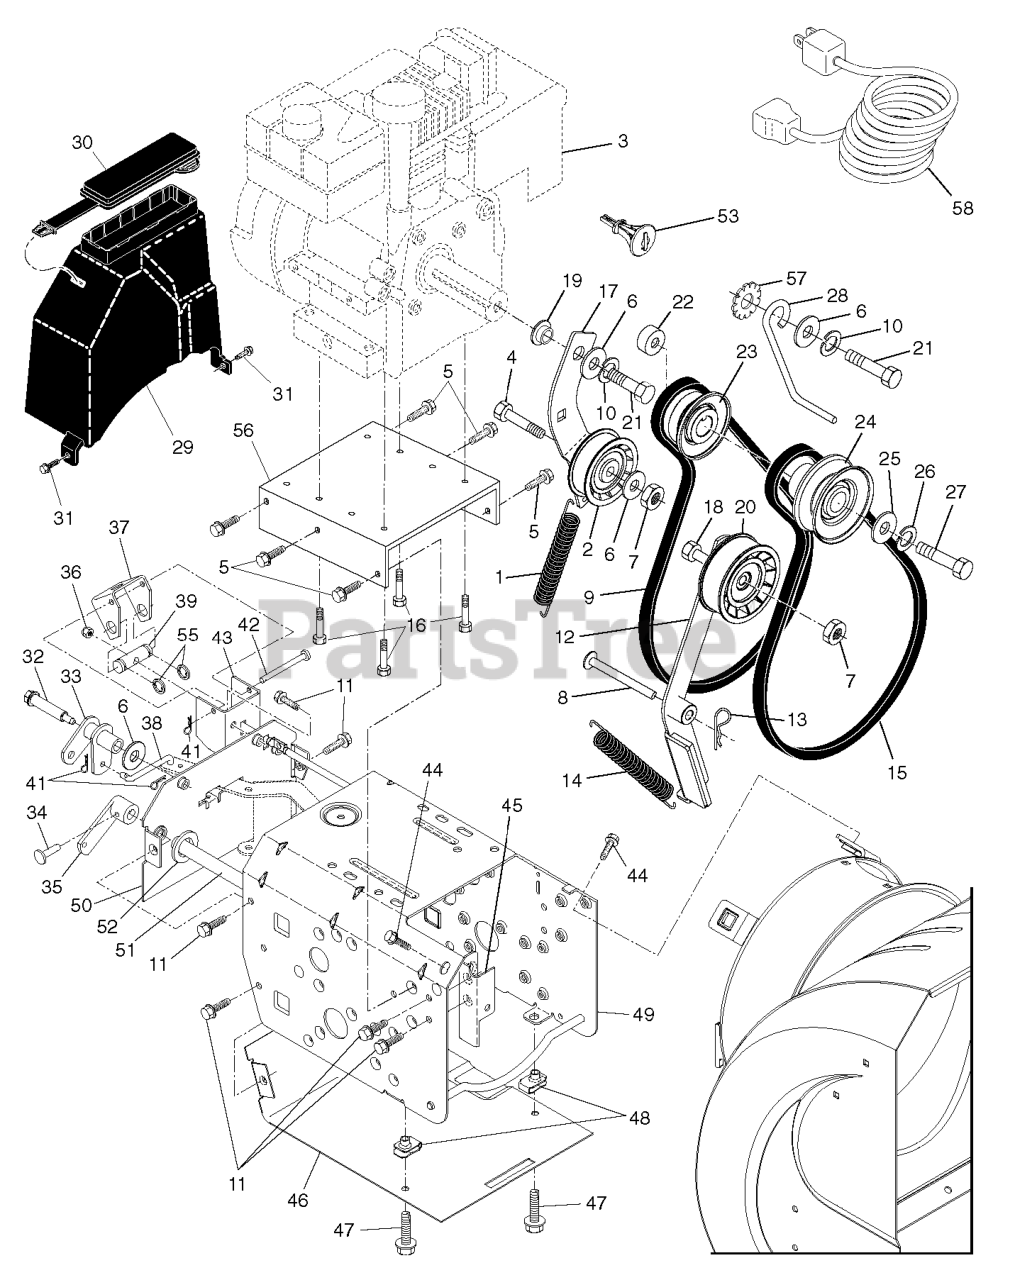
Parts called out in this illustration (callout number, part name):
1	RP SPRING, TRACTION IDLER
2	PULLEY.W/SPACER.2.25
4	BOLT.5/16-18X1-1/4 FULL.THREAD
5	SELF-TAPPING SCREW 5/16-18X3/4
6	STEEL WASHER
7	LOCKNUT 5/16-18
8	PIN, IDLER PIVOT
10	WASHER, LOCK 5/16
11	SCREW, HEX HEAD 5/16-18 X 1/2
12	ARM ASSEMBLY, IMPELLER IDLER
13	RETAINER CLIP PM
14	SPRING, BRAKE
15	BELT.V.IMPELLER
16	BOLT 3/8-16X1-1/8
17	IDLER ARM
18	HEX BOLT
19	BUSHING, IDLER PIVOT
20	PULLEY.W/SPACER.2.75
22	SPACER, ENGINE PULLEY
23	PULLEY,ENGINE TRACTION DRIVE
24	PULLEY, ENGINE IMPELLER DRIVE
25	WASHER, FLAT 3/8
26	LOCKWASHER
27	SCREW, HEX HD 3/8-24 X 1-3/8
28	BELT.GUIDE.RH
29	COVER.ASM.BELT/STORAGE
30	COVER.STORAGE.SNOW
31	SCREW, HEX HEAD 1/4-20
32	BOLT, SHOULDER 5/16-18
33	BELLCRANK SHIFTER
34	CLEVIS PIN
35	ARM, AUGER CONTROL
36	NUT.71038.31-18.HEX.NYLOCK
37	BRACKET, PIVOT
38	LINK, SPEED CONTROL
39	TRUNNION, TRACTION
41	RETAINER CLIP
42	PIN, PIVOT BRACKET
44	SCREW 3/8-16X1
45	BRACKET, IDLER PIVOT
46	PAN, FRAME BOTTOM
47	Screw, Hex Head 5/16-18 x 3/4
48	NUT.SPEED.5/16-18
49	SWITCH.PTO.T
50	PLATE, FRAME END
51	SHAFT, AUGER CONTROL
52	THRUST WASHER
53	KEY.PUSH/PULL.B&S.283707
55	RETAINING RING LT
56	PLATE, ENGINE MOUNTING
57	WASHER EXT TOOTH LOCK 5/16
58	CORD.ELECTRIC.10FT.120V.SNOW
